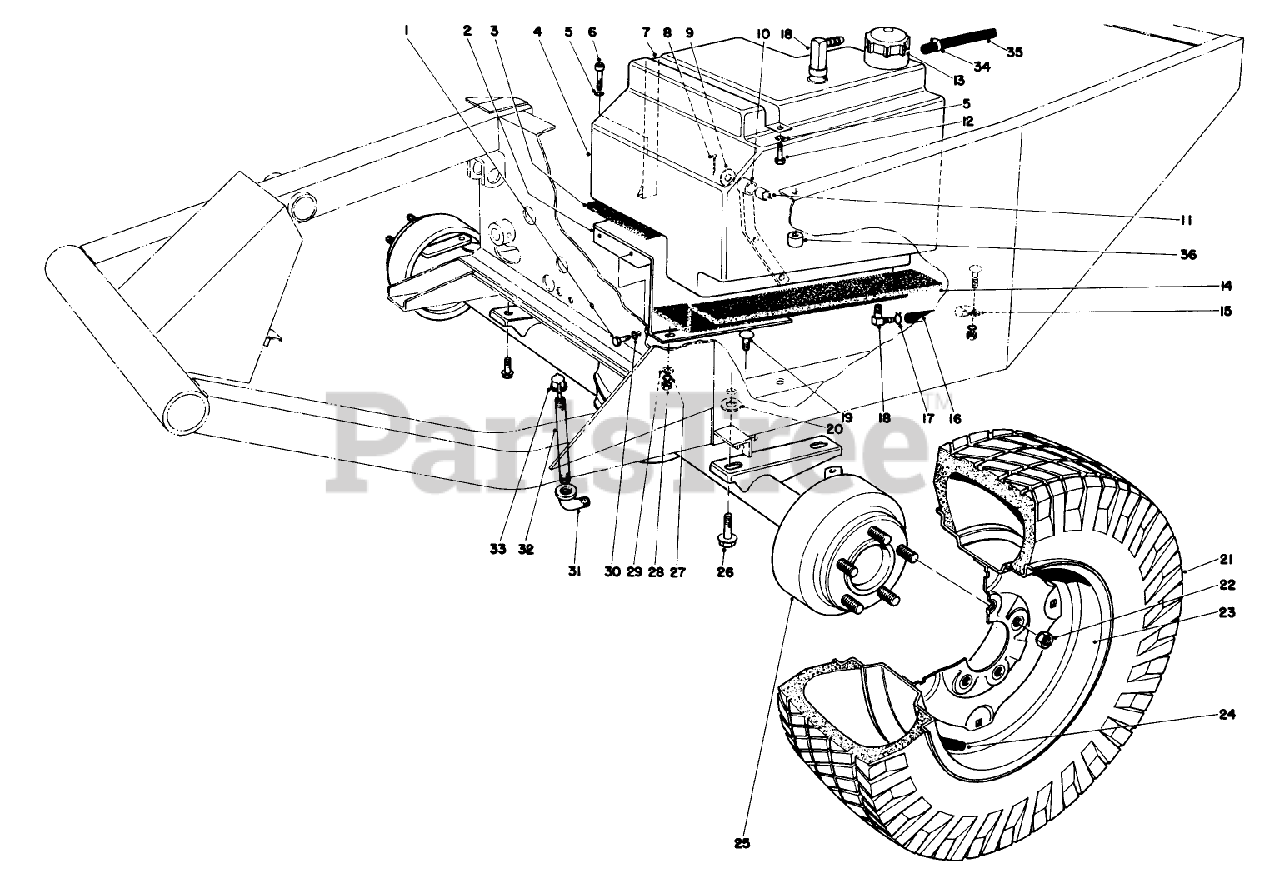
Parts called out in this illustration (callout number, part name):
1	SCREW-HH
2	GAS TANK BASE WA
3	FOAM-SUPPORT, TANK
4	Gas Tank (Incl. Ref. 18)
5	WASHER-LOCK
6	SCREW-HSH
7	STRAP-TANK, FUEL
8	PIN-COTTER
9	WASHER-THRUST
10	Steering Link (Incl. Ref. #11)
11	BUSHING
12	SCREW-HH
13	Gas Cap
14	FOAM-SUPPORT, TANK
15	CLAMP-R
16	HOSE-FUEL
17	CLAMP-HOSE
18	FITTING-ELBOW, 90 DEG
19	BOLT-CARR
20	SPECIAL WASHER
22	NUT-LUG
24	STEM-VALVE
25	Axle
26	SCREW-HHF
27	WASHER-LOCK
28	NUT-HEX
29	WASHER-PLAIN
30	WASHER-LOCK
31	FITTING-ELBOW-90
32	NIPPLE-PIPE
33	DIPSTICK ASM
34	CLAMP-HOSE
35	HOSE-FUEL
36	SPACER
